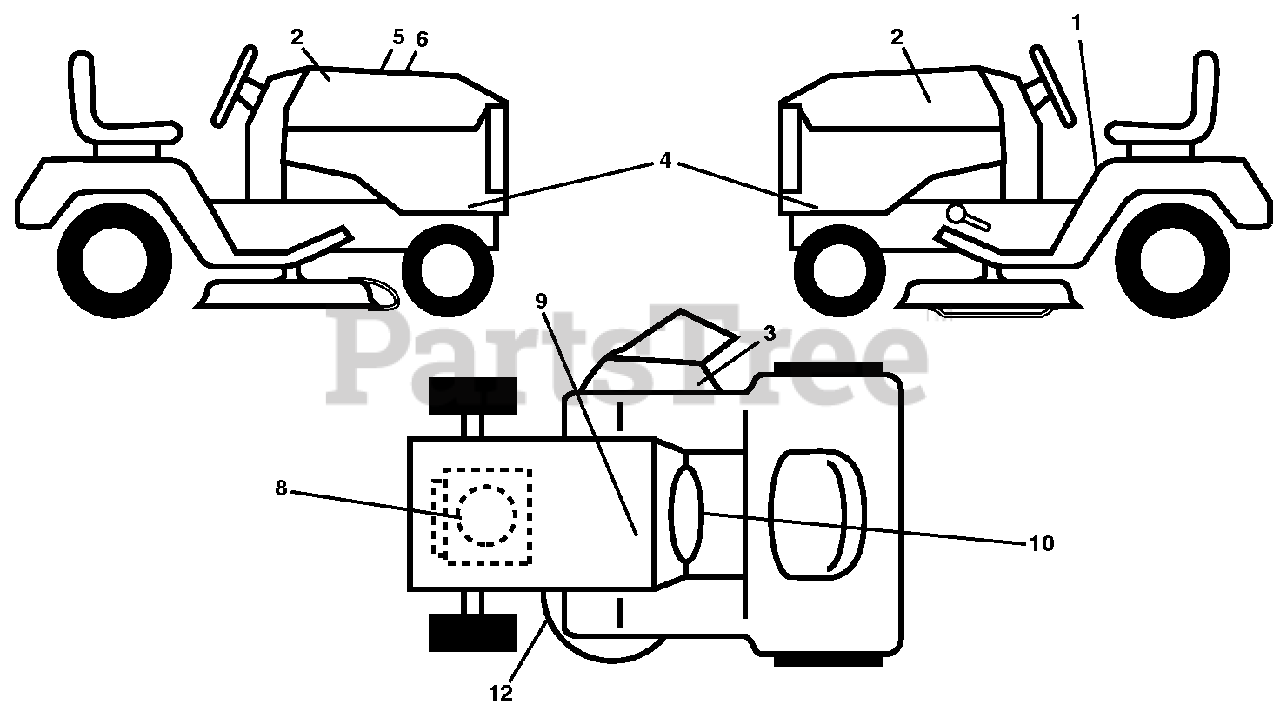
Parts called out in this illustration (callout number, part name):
1	DECAL.FENDER.WARNING.ENGLISH
2	DECAL.BADGE.170MM.TEXTLOGO.
3	DECAL.MOWER.WARN.KEEP.HAND.AWY
4	DECAL SIDEPANEL
5	DECAL.WARNING.CUST.RESP.E85.
6	DECAL.RPL.BSM33.INTK.TLW.42.T2
8	DECAL.ENG.BS.18.5INTK.381713
9	DECAL BTRY SYMBOLS
10	DECAL, WARNING SPARK ARRESTOR
12	DECAL.V-BELT.SCH.42/46"MEC/ELE
